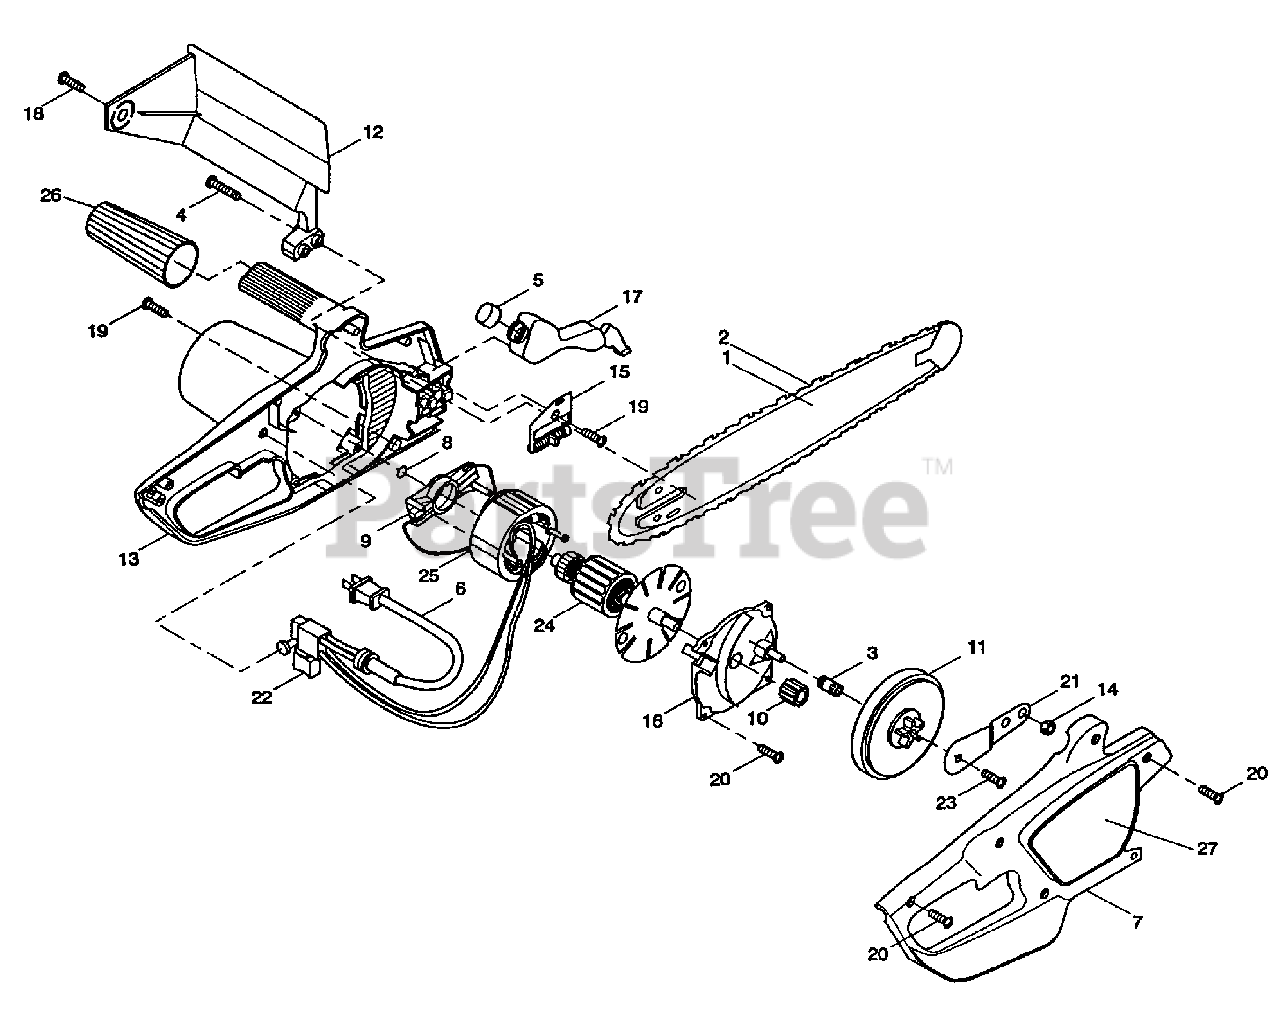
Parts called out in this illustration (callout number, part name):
1	GUIDE BAR-12" (EL-12)
2	SAW CHAIN (EL-12)
3	SPROCKET ROLLER BEARING
4	BOLT-Hex Head
5	CAP-Oil Reservoir
6	CORD (EL-12)
7	SIDE COVER (EL-12)
8	DISC-Thrust (EL-12)
9	BEARING & BRUSH HOLDER (EL-12)
10	GEAR-Drive
11	GEAR-Internal
12	HAND GUARD-Front
13	HOUSING-Motor
15	ADJUSTING PLATE ASSEMBLY
16	BEARING PLATE (EL-12)
17	OIL RESERVOIR
18	SCREW-Tap Pan Head
19	SCREW-Tap Flat Head
20	SCREW-Tap Pan Head
21	SPROCKET SUPPORT
22	SWITCH-Lock-Off
23	SCREW-Shoulder, Pan Head
24	ARMATURE
25	FIELD
26	GRIP- Handle, Front (EL-16)
27	COVER- Sprocket (EL-16)
